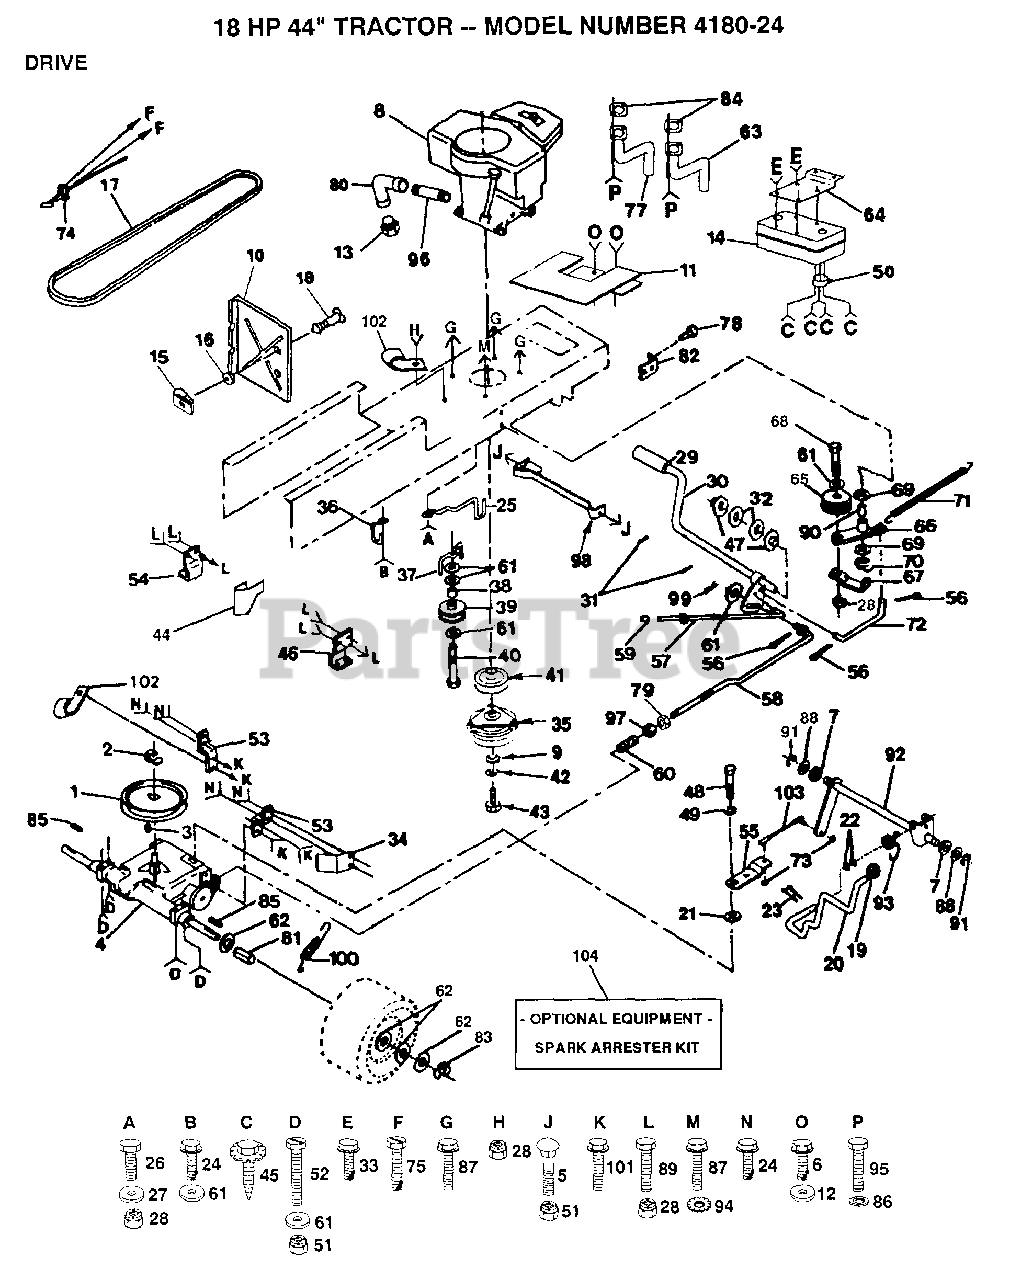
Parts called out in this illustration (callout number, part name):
1	PULLEY TRANSAXLE
2	RING
4	TRANSAXLE PEERLESS MODEL NO
5	BOLT
6	SCREW
7	BUSHING
9	WASHER
10	HEAT SHIELD
12	WASHER
15	RECEPTACLE LT
16	RETAINER LT
17	BELT.GRDRV.94.75
18	STUD.1/4.TURN
19	KNOB T (1/2-HOLE)
21	WASH-SHFT PLT LT
22	WASHER
23	PIN COTTER 1/8
24	SCREW
25	KEEPER.BELT.ENG.L
26	BOLT
27	WASHER
29	PEDAL COVER T
32	WASHER LT
33	SCREW ST
34	"KEEPER,BELT RH"
36	RETAINER BELT
37	BELT KEEPER LT
38	SPACER T
39	PULLEY.IDLER.FLAT
40	BOLT
42	LOCKWASHER
44	KEEPER BELT LH
46	BRKT TRANS RH
47	NYLON BEARING
49	WASHER PM
50	DEFLECTOR.222573
52	BOLT
53	STRAP TORQUE
54	BRKT TRANS LH
55	"ARM,SHIFT"
56	COTTER PIN
57	ROD BRAKE PARK
58	ROD BRAKE
59	PLUNGER CAP T
60	"SPRING,ROD BRAKE"
61	WASHER
62	WASHER
64	BRACKET MUFFLER
66	ARM IDLER
67	RETAIN BELT
69	WASHER LT
70	KLIP RING
71	"SPRING, RETURN LT"
72	"LINK, CLUTCH T"
73	NUT 1/4-28
75	SCREW LT
76	WASHER
78	SCREW
79	NUT
80	ELBOW
81	SPACER HYT
82	BRACKET LT
83	E RING HYT
85	SQ KEY STD
86	LOCKWASHER
87	SCREW LT
88	WASHER D
90	"LY, BEARING"
91	KLIP RING
92	"SHAFT,SHIFTER"
93	"SPRING,TORSION"
94	LOCKWASHER
96	PIPE NIPPLE LT
97	NUT
99	RETAINER M
101	SCREW
102	CLIP T
103	"ROD,TIE "
